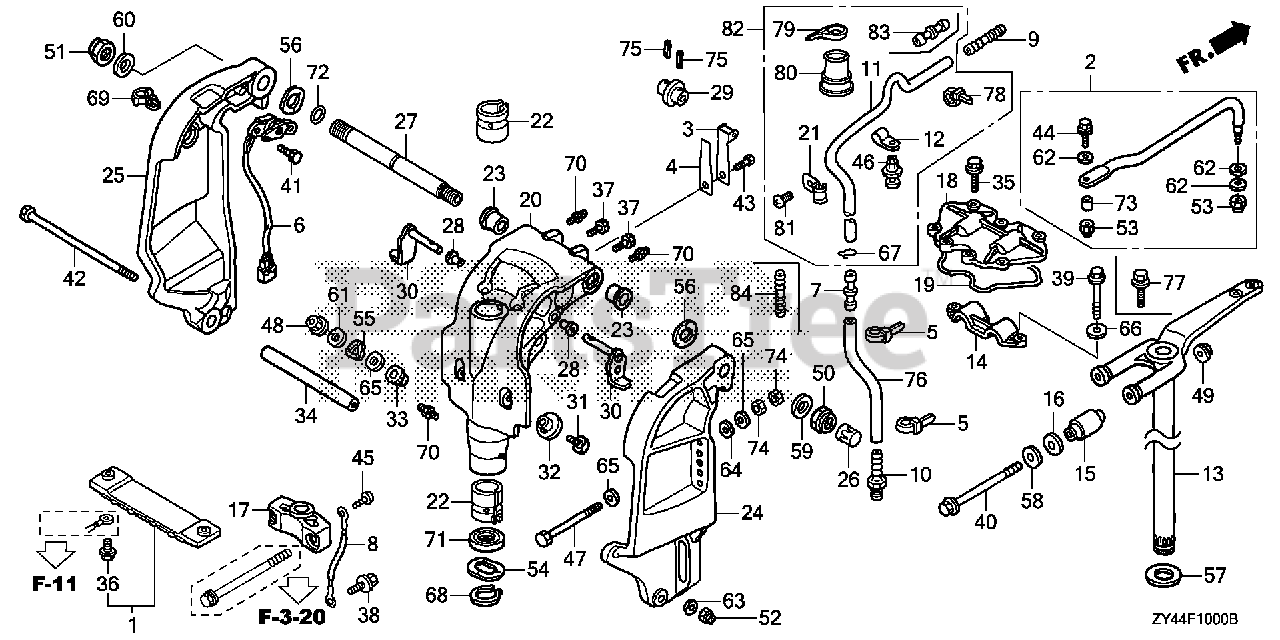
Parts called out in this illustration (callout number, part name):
1	METAL KIT, ANODE
2	ROD KIT, STEERING
3	SPRING, CLICK
4	SPRING, CLICK ASSIST
5	BAND, WIRE
6	SENSOR ASSY., TRIM ANGLE
7	JOINT B, WASHER TUBE (MITSUBA)
8	WIRE, LEAD (1.5X116MM)
9	END, NIPPLE
10	NIPPLE, SENSOR
11	TUBE, SPEED SENSOR
12	CLAMP, SENSOR TUBE
13	FRAME, MOUNTING (XL)
14	HOUSING, MOUNTING (UPPER)
15	MOUNT, RUBBER (UPPER)
16	RUBBER, MOUNT STOPPER (UPPER)
17	HOUSING, CENTER MOUNTING (LOWER) (XL)
18	COVER, MOUNT (UPPER)
19	SEAL, MOUNT COVER (UPPER)
20	CASE, SWIVEL *NH282MU* (XL) (OYSTER SILVER METALLIC-U)
21	CLAMP, TUBE
22	LINER, SWIVEL CASE
23	BUSH, SWIVEL CASE
24	BRACKET, R. STERN *NH282MU* (OYSTER SILVER METALLIC-U)
25	BRACKET, L. STERN *NH282MU* (OYSTER SILVER METALLIC-U)
26	CAP, TILTING BOLT
27	SHAFT, TILTING
28	BUSH, TILT ARM
29	BRACKET, TILTING
30	STOPPER, TILT
31	RECEIVER, THRUST
32	BUSH A, THRUST RECEIVE
33	BUSH B, THRUST RECEIVE
34	COLLAR, CYLINDER (LOWER)
35	BOLT, FLANGE (6X20)
36	BOLT, FLANGE (6X23)
37	BOLT (1/4-28UNF)
38	BOLT, FLANGE (6X12)
39	BOLT, HEX. (10X32)
40	BOLT, HEX. (12X200)
41	BOLT, FLANGE (6X20)
42	BOLT, HEX. (10X235)
43	BOLT, HEX. (6X14)
44	BOLT (3/8-24UNF)
45	SCREW, PAN (6X8)
46	SCREW, RIVET (5X10)
47	BOLT, HEX. (12X119)
48	NUT, SELF-LOCK (6MM)
49	NUT, FLANGE (12MM)
50	NUT, SELF-LOCK (7/8-14UNF)
51	NUT, SELF-LOCK (25X2.0)
52	NUT, SELF-LOCK (10MM)
53	NUT, SELF-LOCK (3/8-24UNF)
54	WASHER, WAVE (40MM)
55	WASHER, WAVE (12MM)
56	WASHER, WAVE (26MM)
57	WASHER, THRUST (34MM)
58	WASHER, MOUNTING STOPPER (UPPER)
59	WASHER (7/8")
60	WASHER (25MM)
61	WASHER, PLAIN (6MM)
62	WASHER (10MM)
63	WASHER, PLAIN (10MM)
64	WASHER, PLAIN (12MM)
65	WASHER, PLAIN (12MM)
66	WASHER, PLAIN (10MM)
67	CLIP, TUBE (B8)
68	CIRCLIP (OUTER) (39MM)
69	CLIP, WIRE HARNESS
70	NIPPLE, GREASE
71	OIL SEAL (39.5X52X6) (ARAI)
72	O-RING (15.54X2.62)
73	COLLAR, STEERING ROD
74	NUT, HEX. (12MM)
75	PIN, SPRING (3X20)
76	BULK HOSE, VACUUM (5X3000) (5X340)
78	BAND, WIRE
79	BAND (BLACK 3.5X140)
80	GROMMET, CASE (LOWER) (C)
81	SCREW, PAN (6X8)
